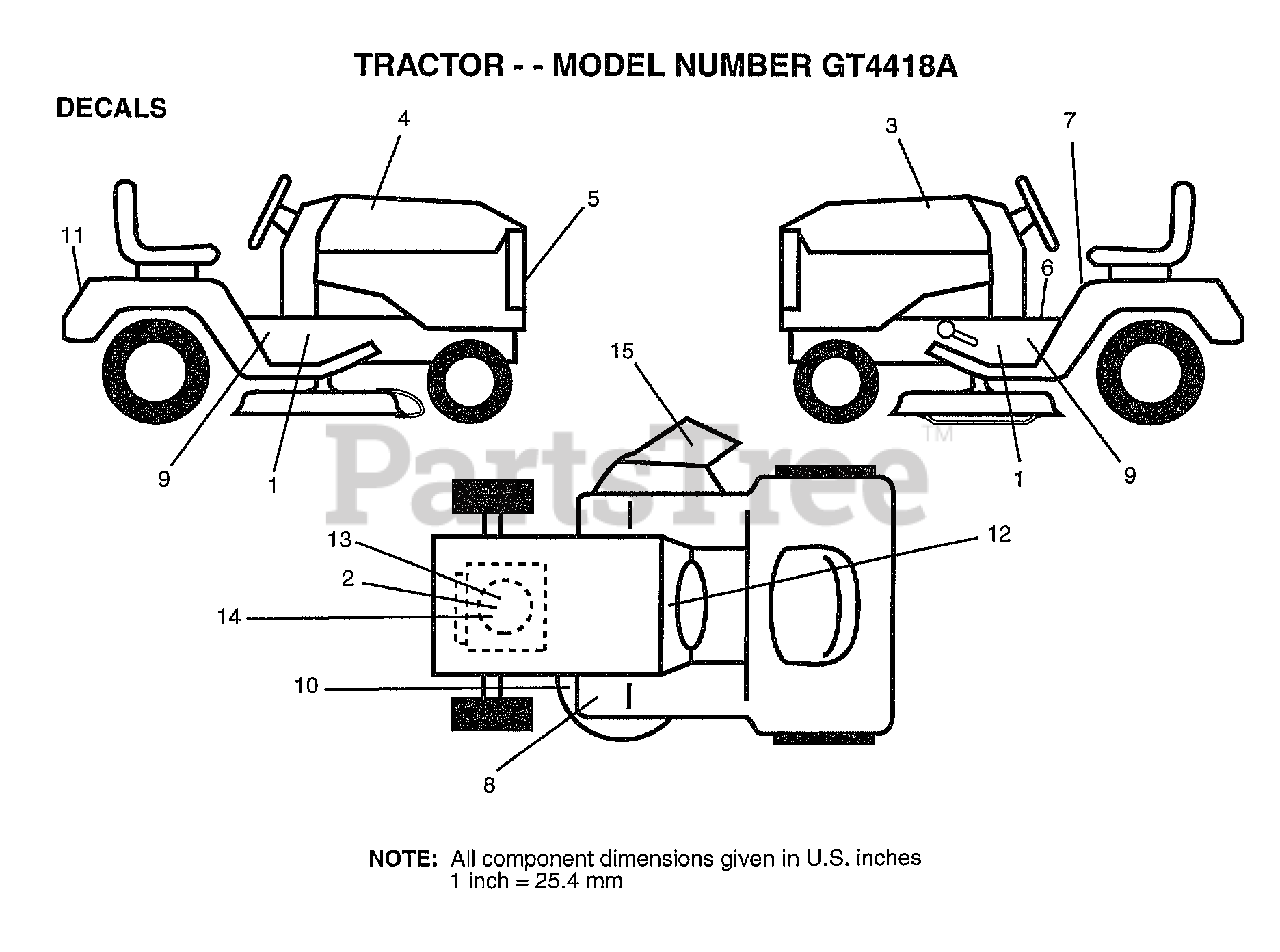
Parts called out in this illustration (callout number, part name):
2	DECAL.ENG.272757
3	DECAL HD LH
4	DECAL HD RH
5	DECAL LOGO GRILLE
6	DECAL BRAK PARK
7	DECAL CAUT FEND
8	DECAL CLUT/BRAKE
9	DECAL CHASSIS YT
10	"DECAL.V.BELT.44"""
11	DECAL.FEN.GT.KMAR
12	DECAL INST OP DAS
13	DECAL.ENG.272101
15	DECAL DANGER CT/F
16	DECAL DECK MULCH
